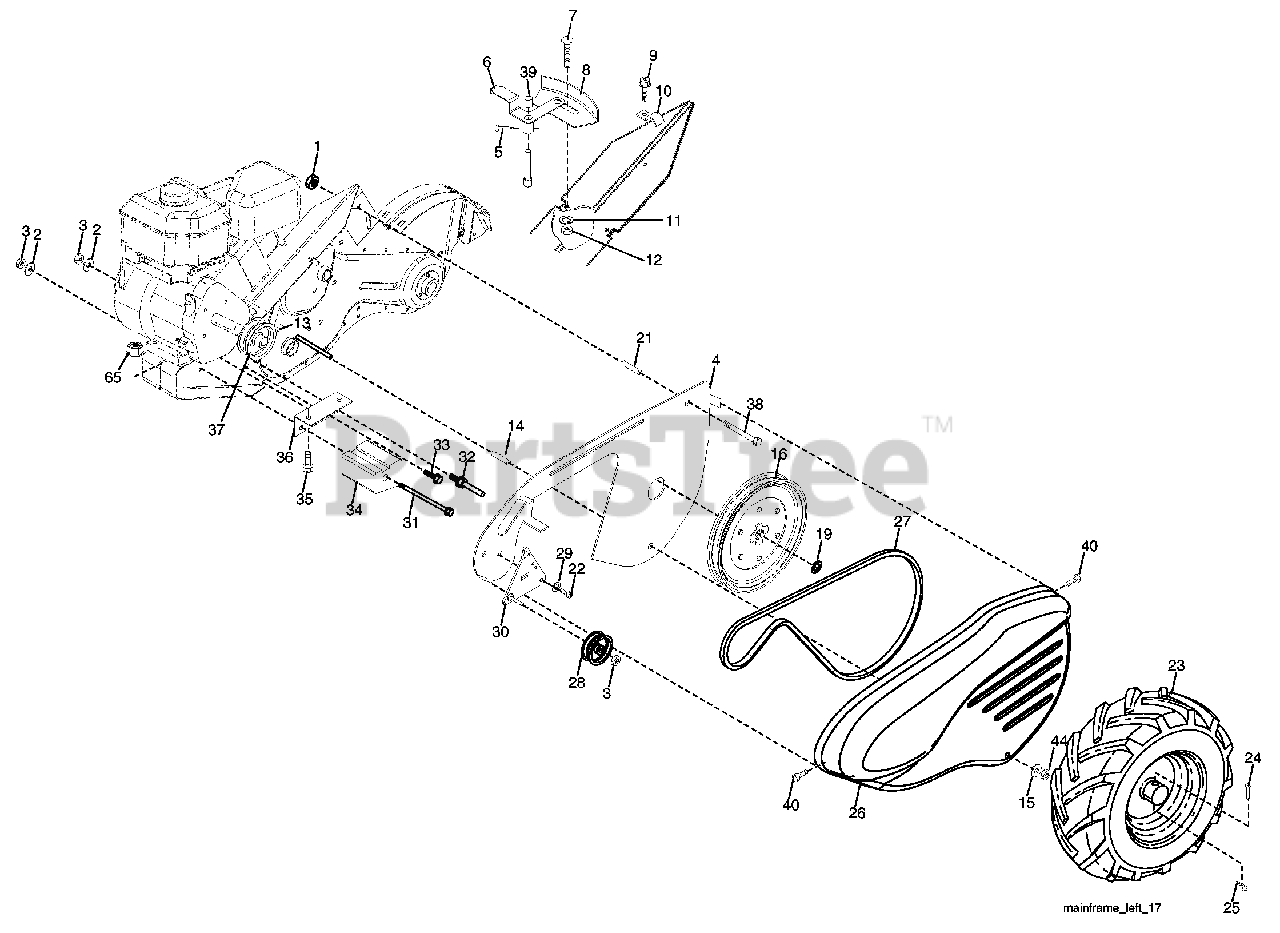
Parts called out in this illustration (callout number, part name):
1	Nut, Keps 5/16-18
2	Washer, Lock 3/8
3	Nut, Hex 3/8-16
4	Shield, Inner Belt Guard RT
5	Pin Spirol Flared
6	Lever, Shift
7	Bolt, Carriage 1/4-20 x 1/2 Gr. 5
8	Plate, Shift Indicator
9	Screw, Hex, Washer Head, Slotted #10-24 x 1/2
11	Washer, Lock 1/4
12	Nut, Hex 1/4-20
13	Screw, Set, Hex 5/16-18 x 3/8
14	Spacer, Split0.327 x 0.42 x 2.09
15	Washer 11/32 x 11/16 x 16 Ga.
16	Sheave, Transmission
19	Retainer, Ring
21	Spacer, Split
22	Bolt, Fin Hex 5/16-24 UNF x 1/2
23	Rim
23	Tire Valve
24	Rivet, Drilled
25	Clip, Hairpin
26	Guard, Belt
27	Belt, V
28	Pulley, Idler
29	Ring, Klip
30	Bracket, Idler
31	Bolt, Hex 5/16-16 x 12
32	Shaft, Idler Arm
33	Bolt, Hex 3/8-16 x 1
34	Counterweight, L. H.
35	Bolt, Hex 5/16-18 x 1-1/2
36	Bracket, Reinforcement, L. H.
37	Sheave, Engine
38	Bolt, Fin Hex 5/16-18 UNC x 2-3/4
39	Cap, Plunger Blk
40	Screw Hex Wsh Slt #10-24 x 1/2
44	Nut Lock Hex w/Ins 5/16-18 Unc PL
65	Nut Lock Hex Flange
